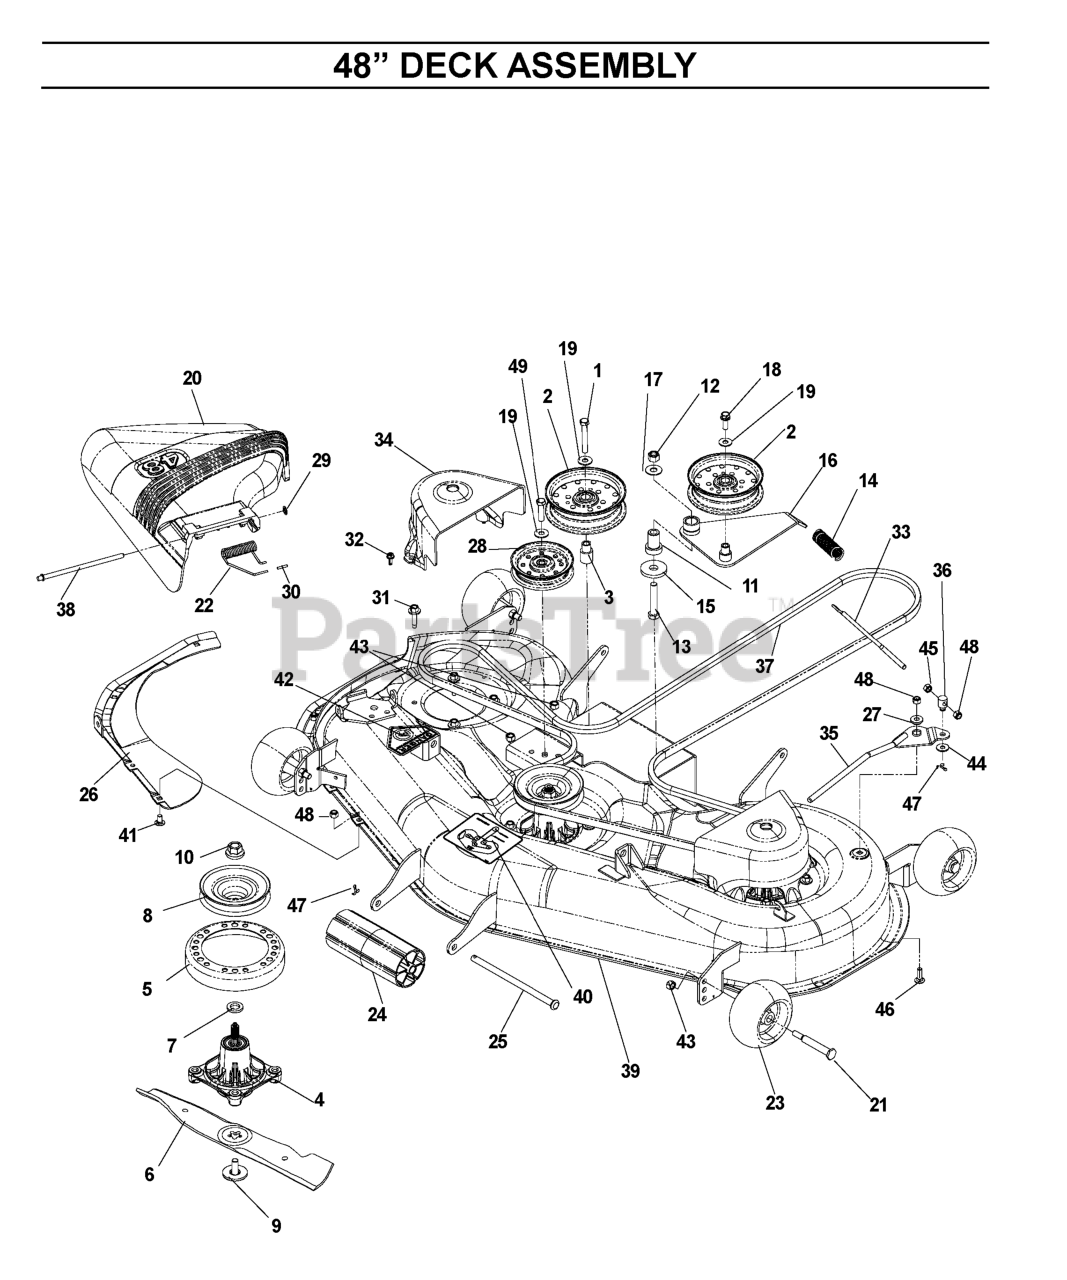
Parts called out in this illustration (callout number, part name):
1	SCREW 3/8C X 2 3/4 HEX CAP
2	IDLER PULLEY
3	IDLER BUSHING
4	MANDREL ASM
5	STRIPPER-ROUND-UNIVERSAL
6	48" HI-LIFT BLADE
7	WASHER-SPACER
8	PULLEY.DRIVEN.DECK.48'
9	BOLT 7/16 ASM BLADE
10	LOCKNUT - 9/16
11	IDLER SPINDLE
12	NUT 1/2-13 HEX NYLOC ZD
13	SCREW, 1/2C X 3 HEX CAP
15	WASHER, SUPPORT
16	DECK IDLER ARM
17	WASHER 1/2 FLAT
18	4CS 3/8C X 1 SERRATED HEAD
19	WASHER 5/16 FLAT
20	DEFLECTOR.ASM.BLACK.48"
21	BOLT, SHOULDER
22	TORSION SPRING
23	WHEEL GAGE DONUT
24	NOSE ROLLER 48"
25	NOSE ROLLER ROD
26	VORTEX MOWER BAFFLE
27	PIVOT BUSHING
28	PULLEY.IDLER.FLAT.46.PR.DR.
29	PUSH NUT
30	CAP-SLEEVE
31	WASHER HEAD SCREW
32	SCREW- 1/4-20 X 5/8
33	TENSION RELIEF LINKAGE
34	BELT SHIELD
35	TENSION RELIEF LEVER BLK
37	BELT, DECK
38	ROD.HINGE
39	DECK SVC W/DECALS HUSQ ORANGE
40	DECAL, BELT ROUTING
41	CARRIAGE BOLT 5/16C X 5/8"
42	DECAL, CPSC
43	NUT 3/8-16 NYLOC
44	WASHER 3/8 SAE FLAT
45	NUT 5/16C HEX
46	RHSNB 5/16C X 1
47	RP_COTTER PIN 1/8 X 3/4
48	NUT 5/16 NYLOC
49	HCS 3/8-16 X 1 3/4 GR5
